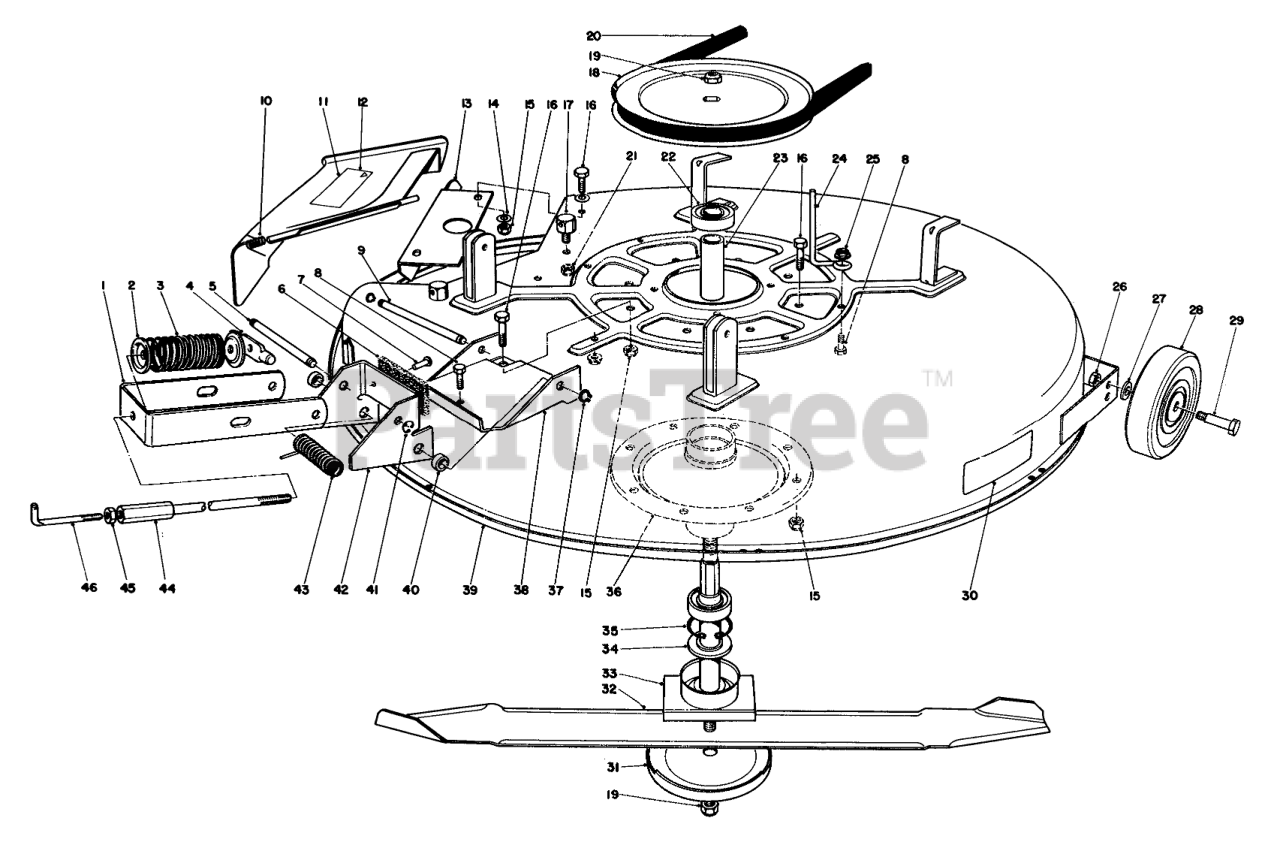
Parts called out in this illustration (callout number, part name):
1	Bracket-Engagement
2	RETAINER-SPR. TOP
3	SPRING-COMPRESSION
4	SHAFT-DECK ADJ.
5	Pin-Clevis
6	BRAKE PAD
7	RIVET .187 X 7/16 BRASS
8	SCREW-HH
9	CLEVIS PIN
10	SPRING
11	Deflector Assembly (Incl. Ref. #12)
12	Decal
13	Baffle Deck
14	WASHER-PLAIN
15	NUT-LOCK, NI
16	SCREW-HH
17	POST-PIVOT
18	PULLEY
20	V-BELT, DECK
21	NUT-LOCK, SIDE
22	BEARING-BALL
23	Spacer-Bearing
24	BELT GUIDE
25	NUT-LOCK, HHF
26	Nut
27	WASHER-FLAT
28	DECK WHEEL
30	DECK DECAL
31	Cup
32	Blade
33	SPINDLE SHAFT WA
34	SPACER-SPINDLE
35	RING-RETAINING
36	Spindle Body
37	RING-RETAINING
38	DECK ENGAGE CHANNEL R
39	Cutter Deck
40	DECK BRAKE SPACER
41	E-RING
42	Support Deck Brake Assembly (Incl. Ref. #6 & 7)
43	SPRING
44	ADJ HUB WA
45	NUT-JAM
46	ADJ. ROD
